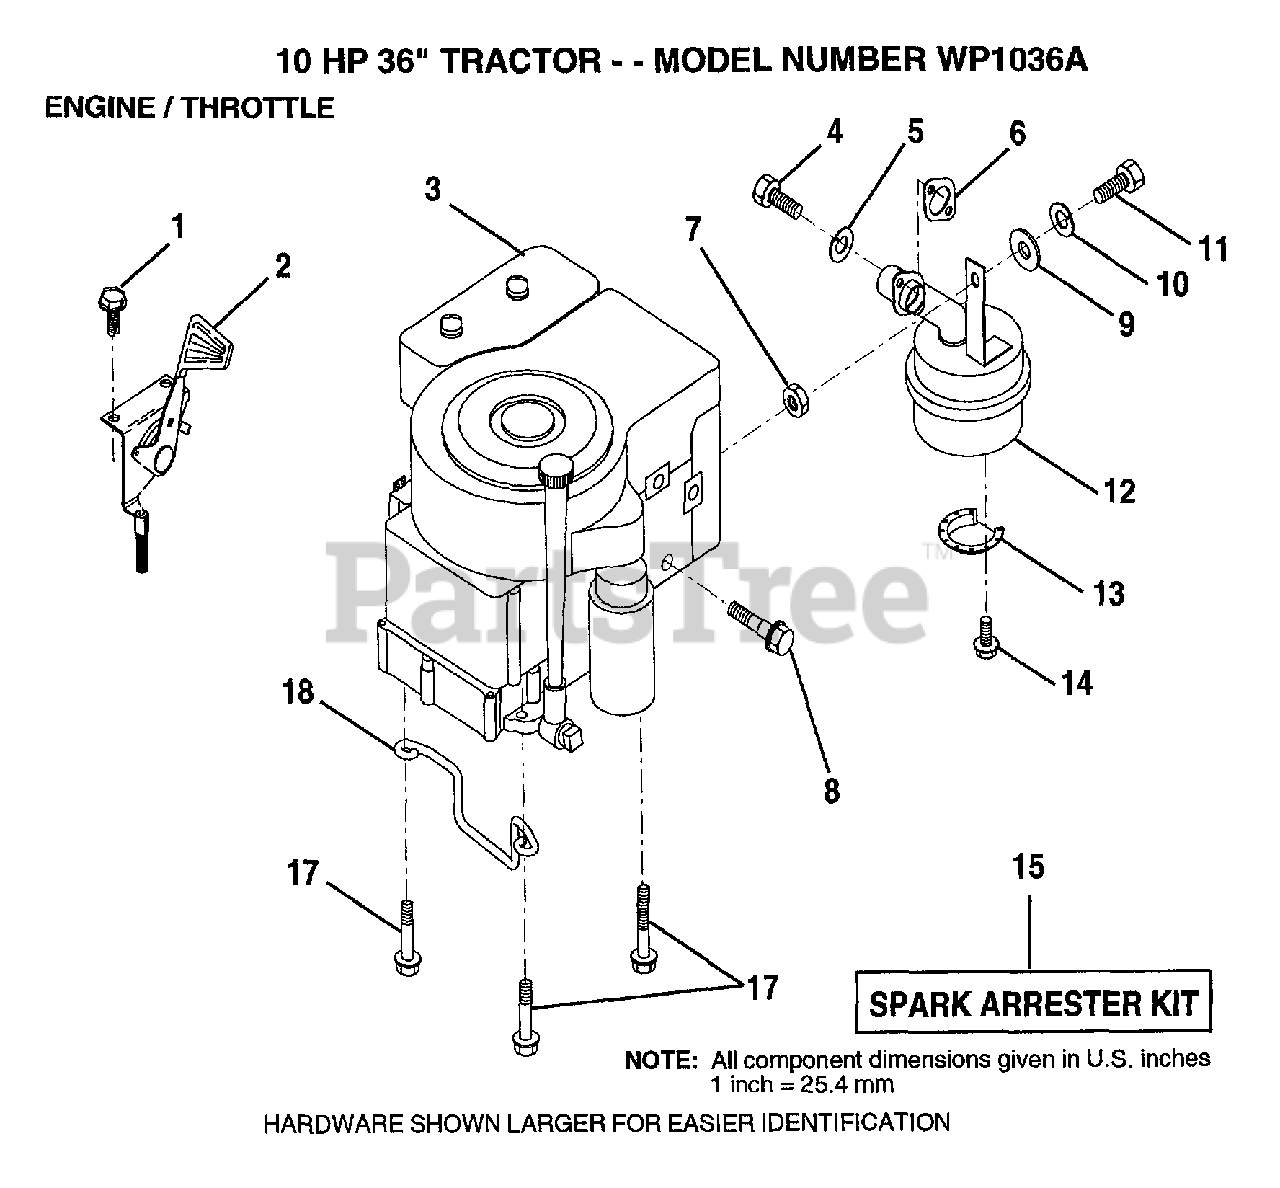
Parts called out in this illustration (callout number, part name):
1	SCREW
2	THROTTLE CONTROL
4	SCREW
5	LOCKWASHER
7	NUT.HEX.5/16-18
8	BOLT T
10	LOCKWASHER
12	MUFFLER
13	DEFLECTOR.222573
17	SCREW LT
18	"KEEPER,DR BELT GR"
